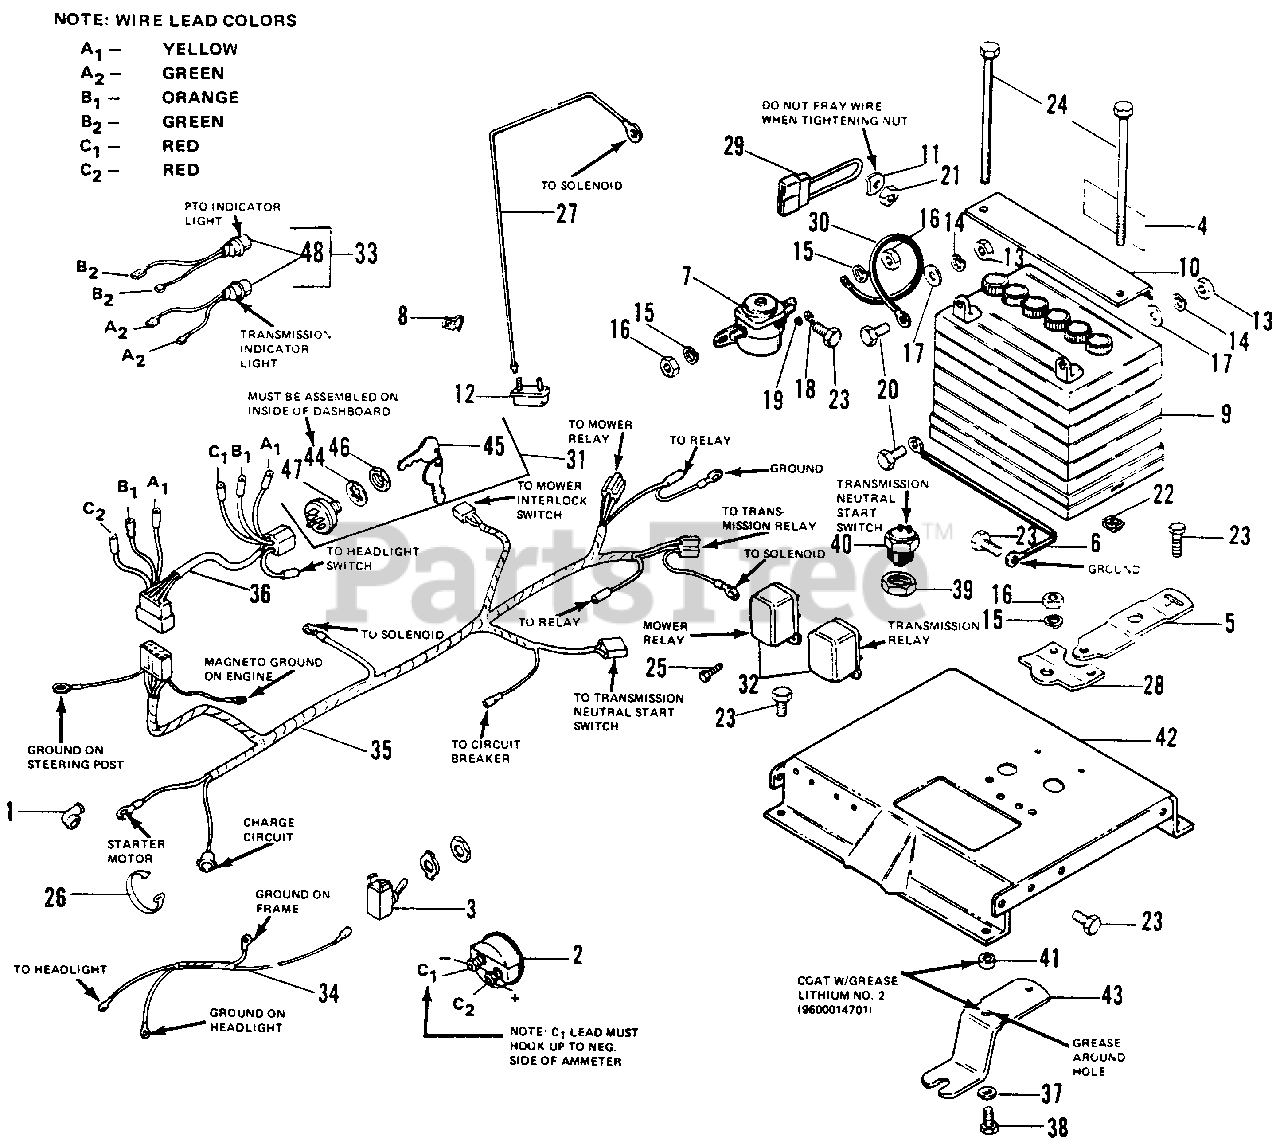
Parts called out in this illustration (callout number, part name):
1	COVER, Terminal
2	AMMETER
3	SWITCH, Toggle
4	FILM, Battery
5	BRACKET, Switch
6	CABLE, Ground
8	CLIP, Speed
10	CLAMP, Battery
11	WASHER, Cup
12	BREAKER, Circuit
13	NUT, Hex, Full, 1/4-20
14	LOCKWASHER, 1/4
15	LOCKWASHER, 5/16
16	NUT, Hex, Full, 5/16-18
17	WASHER, Plain, 1/4
18	NUT, Hex, Full, 10-32
19	LOCKWASHER, Ext. No. 10
20	CAPSCREW, Hex, Hd., 25-2A x .75
21	LOCKNUT, Hex, full, 5/16-18
22	SPEED NUT, 1/4-20
23	SCREW, Washer, Hd. Taptite, 1/4-20 x 3/8
24	CAPSCREW, Hex, 1/4-20 x 7
25	SCREW, Hex, Washer Hd., Taptite No. 10-24 x 1/2
27	WIRE ASSEMBLY
28	LEVER, Pivot Shift
29	WIRE, Mower Bypass
31	SWITCH, Ignition
32	RELAY, 12 Volt
33	LIGHT, Indicator
34	WIRE ASSY., HEADLIGHTS
35	HARNESS, Lower
36	HARNESS, Upper
38	CAPSCREW, Hex, 5/16-18 x 1
39	LOCKNUT, 9/16-17 Palnut
40	SWITCH, Interlock
42	SUPPORT, Frame
43	SWITCH, Lever
44	LOCKWASHER, Internal, 5/8
45	KEYS, Ignition (On Ring)
46	NUT, Hex, Special, 5/8-32
47	SWITCH
48	LENS, Green
